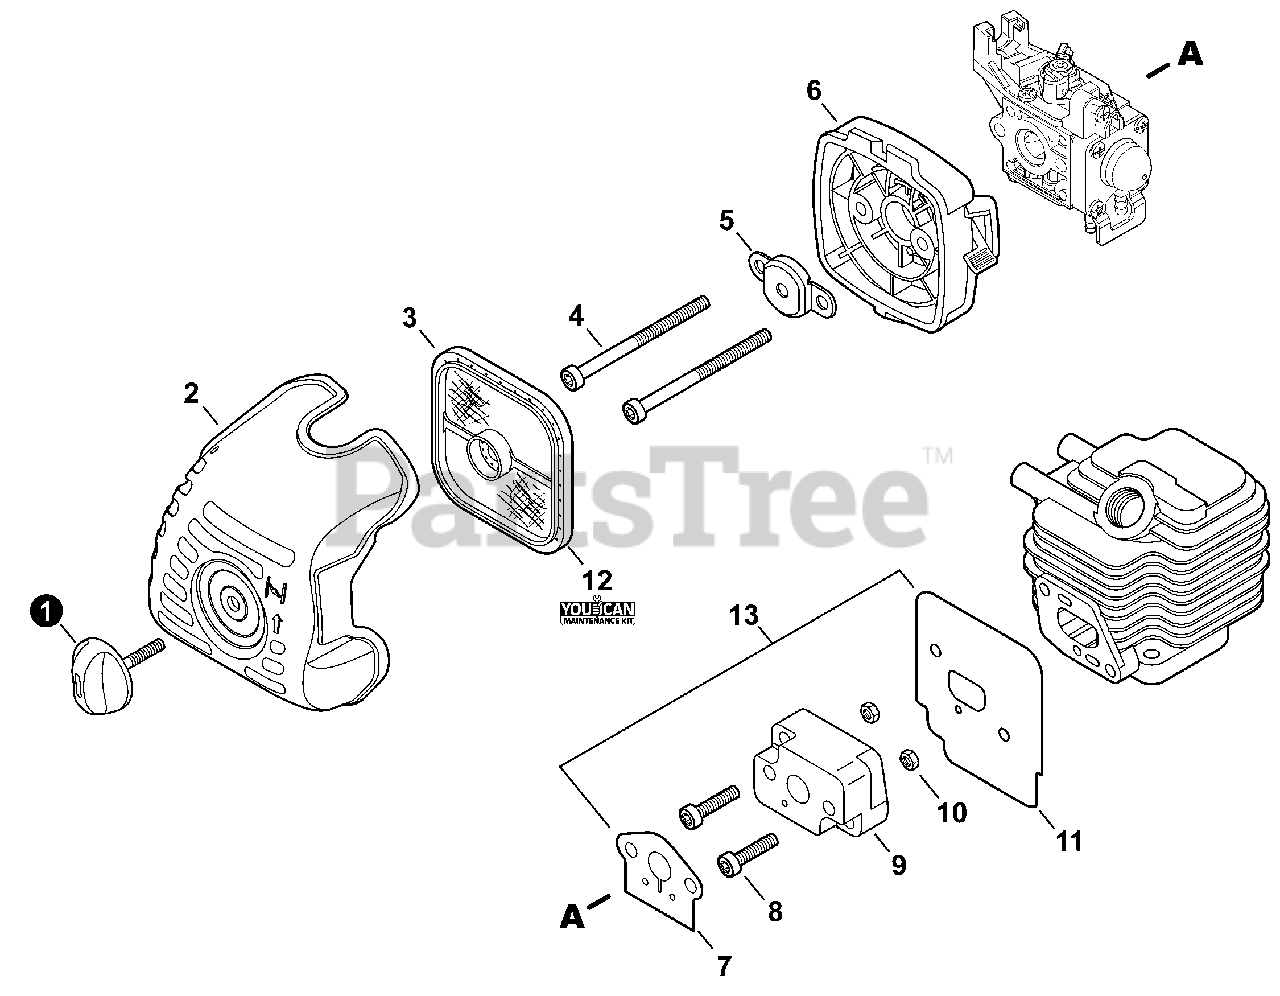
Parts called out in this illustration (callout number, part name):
1	THUMBSCREW
2	COVER, AIR FILTER
3	FILTER, AIR - DOUBLE LAYER
4	BOLT, TORX 5x65
5	PLATE, PREVENT
6	CASE ASSY, AIR FILTER
7	GASKET, INTAKE
8	BOLT, TORX 5x20
9	INSULATOR, INTAKE
11	HEAT SHIELD, INTAKE
12	TUNE-UP KIT - YOUCANT
13	GASKET KIT: ENGINE, INTAKE, EXHAUST
